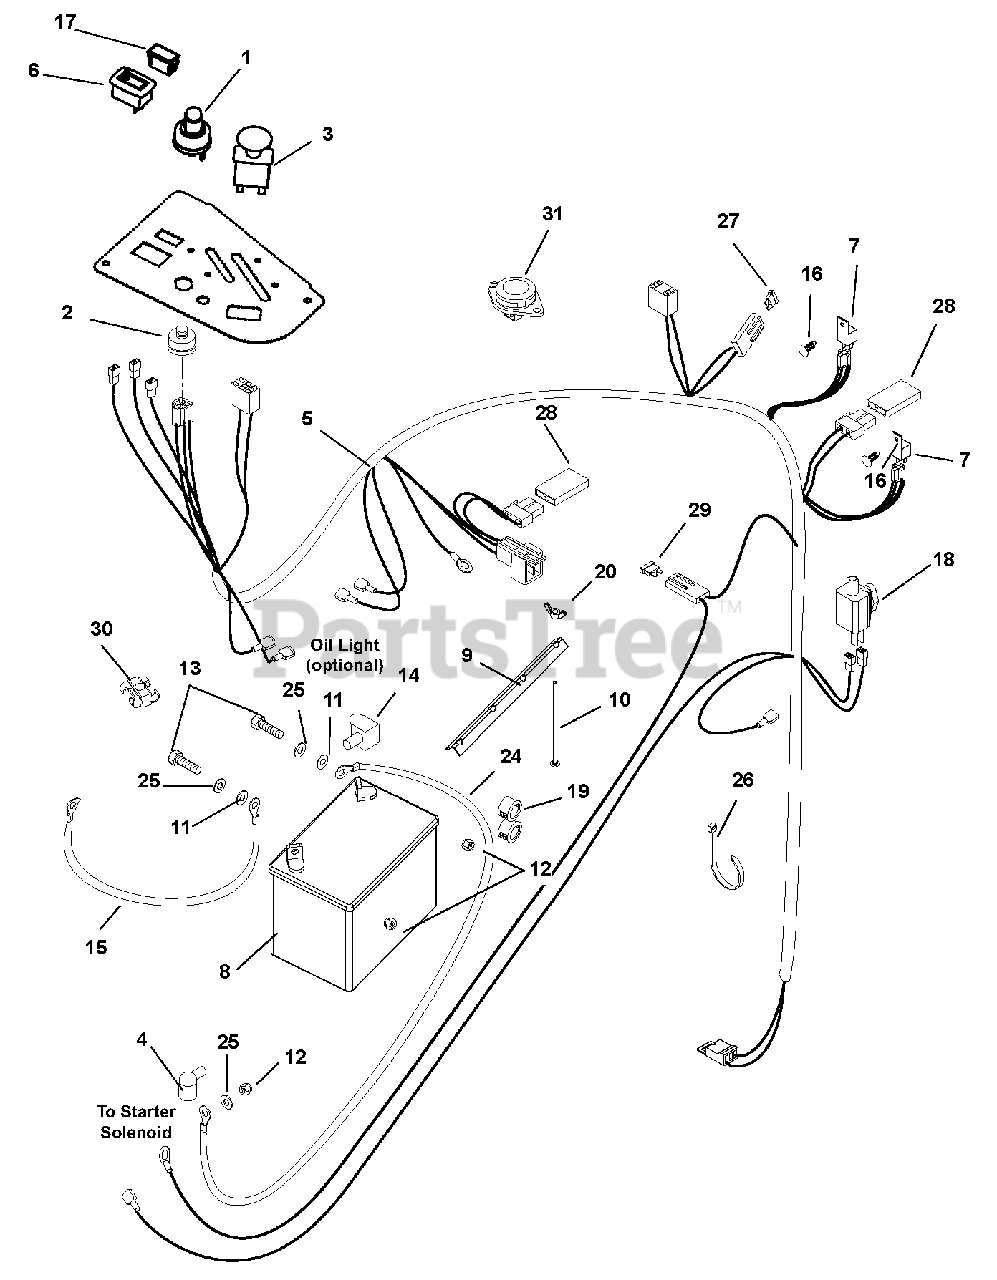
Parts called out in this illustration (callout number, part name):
1	Key, with Shield
2	Switch, Ignition
3	Switch, Clutch
4	Boot, Eyelet Terminal
5	Harness, CZ Remote SOL.
6	Hour Meter, with Maintenance
7	Relay, Sealed with Diode
9	Hold Down
10	Bolt, Round Head Square Neck .25-20 x 7.50
11	Washer, Flat Steel .281 x .620 x .065
12	Nut, Hex .25-20
13	Bolt, Hex .25-20 x .75 Grade 5
14	Insulator
15	Cable, Negative Battery
16	Rivet, .25 Nylon Panel
17	Plug, Hole .50 Diameter
18	Switch, Single Pole (N.O.) – Brake Switch
19	Bushing, Panel Snap .687 x .875 x .56
20	Nut, Locking Wing .25-20
21	Screw, Tapping .25-20 x .50 Hex Washer Head
22	Nut, Jam .31-24
23	Washer, Star Washer .31 x .078 Regular
24	Cable, Starter
25	Washer, Lock .25 x .062
26	Tie, Cable LG 5.50
27	Fuse 20AMP
28	Diode, Connector Shell
29	Fuse, 25 AMP
30	Clip,T,.31-.38
31	Switch, Seat
